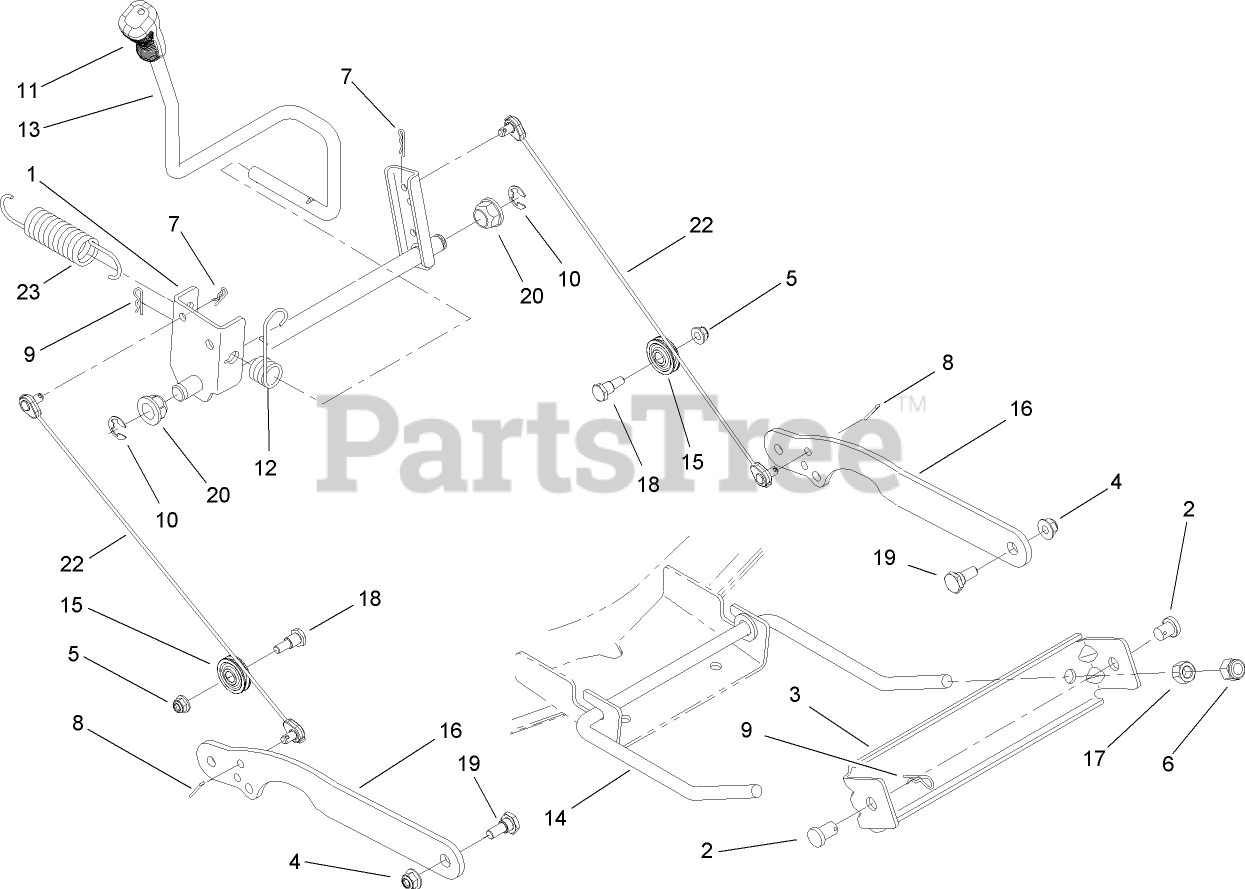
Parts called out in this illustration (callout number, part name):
1	LIFT SHAFT ASM
2	PIN-BRACKET, LIFT
3	BRACKET-STABILIZER
4	NUT-LOCK, FLANGE
5	NUT-LOCK, FLANGE
6	NUT-LOCK, HEX (NYLON)
7	PIN-COTTER
8	PIN-COTTER
9	PIN-HAIR
10	RING-E
11	GRIP-HANDLE
12	SPRING-TORSION
13	HANDLE-LIFT
14	ROD-FRONT, ADJUST
15	PULLEY-ROLLER
16	LINK-DECK, LIFT
17	NUT-HEX
18	BOLT-SHOULDER
19	BOLT-SHOULDER
20	BEARING-FLANGE
22	CABLE-LIFT
23	SPRING-LIFT, ASSIST
